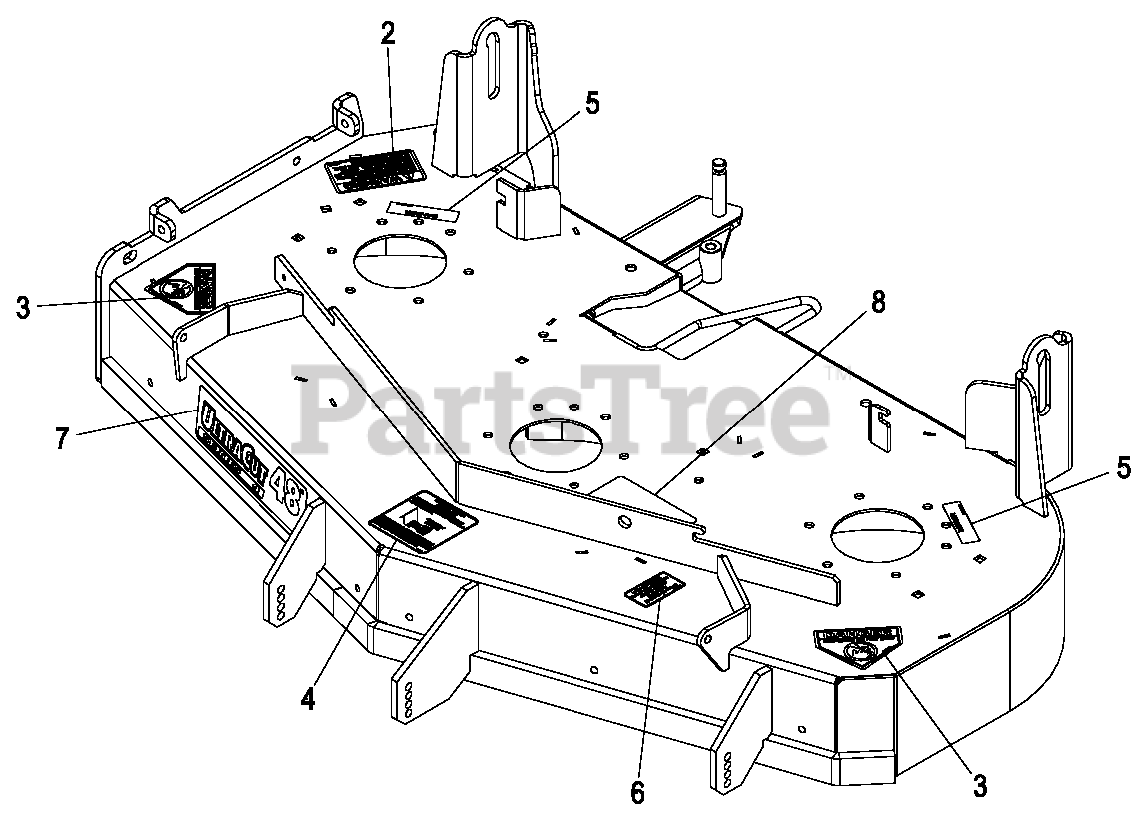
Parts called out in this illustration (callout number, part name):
2	DECAL-WARNING, DISCHARGE
3	DECAL-DANGER
4	DECAL,ANTISCALP
5	DECAL-COVER, MISSING
6	DECAL,BOLT TORQUE
7	DECAL,ULTRACUT 48 SERIES
8	DECAL-BELT ROUTING
